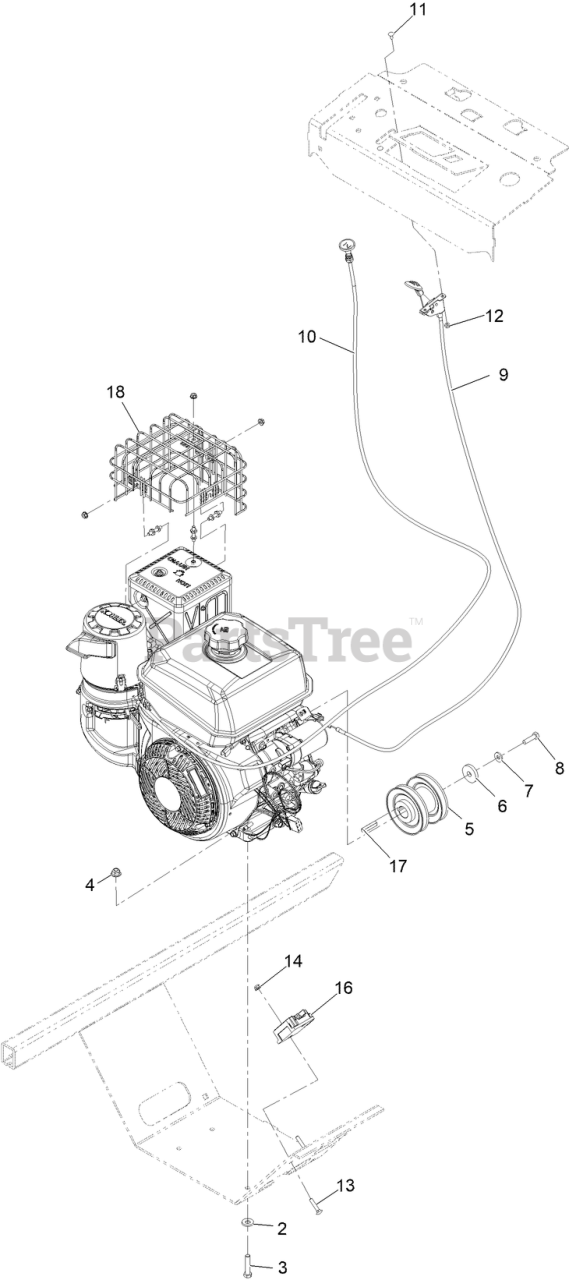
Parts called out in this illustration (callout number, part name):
2	WASHER-BELLEVILLE
3	SCREW-HH
4	NUT-HF, NI
5	PULLEY
6	WASHER-CLUTCH
7	WASHER-SPRING
8	SCREW-HH
9	CONTROL-THROTTLE
10	CABLE-CHOKE, PUSH/PULL
11	BOLT-CARR
12	NUT-LOCK, NI
13	SCREW-CARR
14	NUT-HF
16	REGULATOR
17	KEY-SQUARE, 7MM
18	KIT-MUFFLER BIRDCAGE
